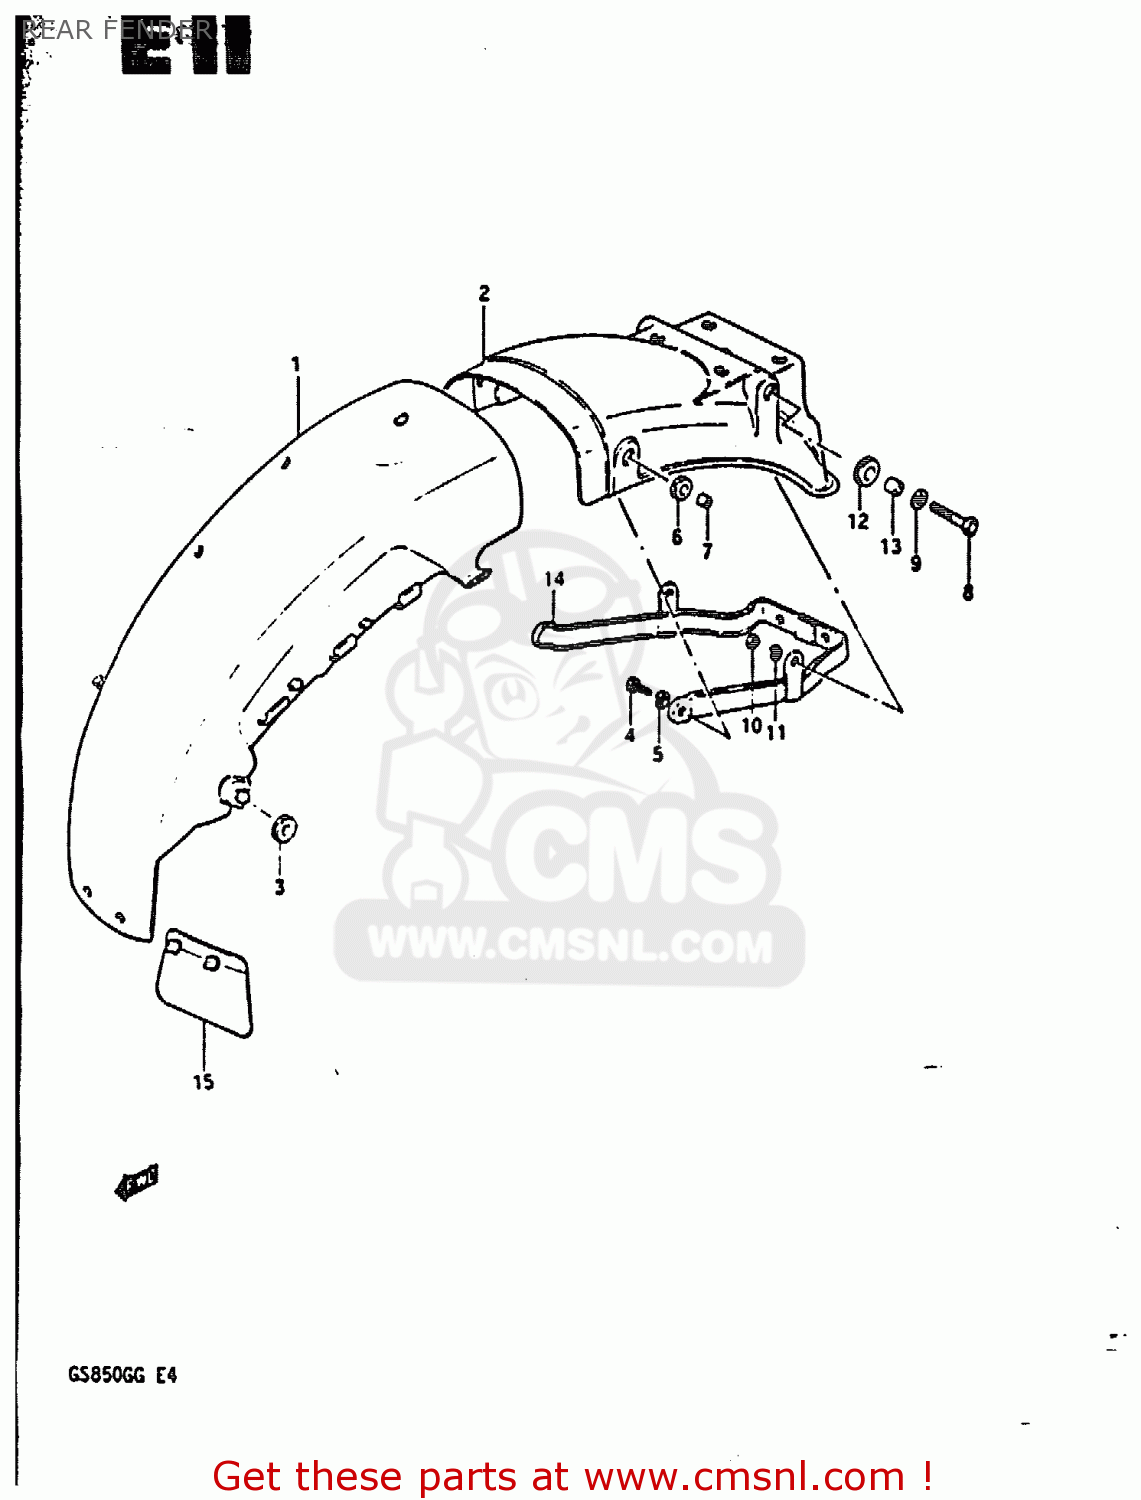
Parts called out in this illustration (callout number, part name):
1	BODY,RR FENDER FR
2	FENDER,REAR
3	CUSHION
4	BOLT, UPPER
5	WASHER,LOCK
6	CUSHION
7	SPACER(6.1X9X7.5)
8	BOLT (8X30)
9	WASHER
10	NUT
11	LOCK WASHER
12	CUSHION
13	SPACER (8.2X12X7.5)
14	REINFORCEMENT,REAR FENDER
15	GUIDE,RR FENDER MUD
